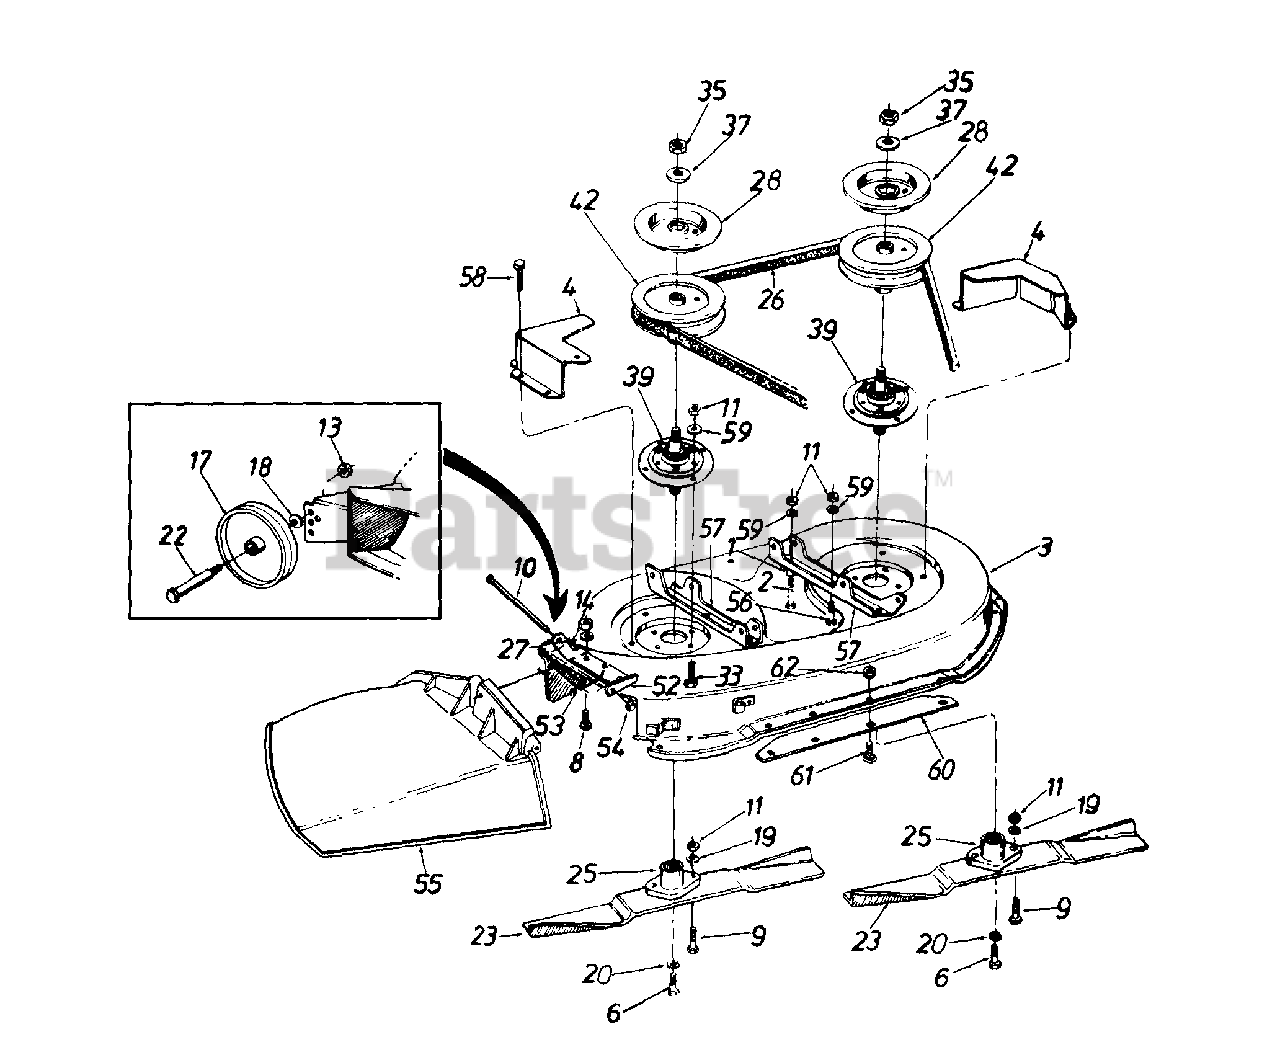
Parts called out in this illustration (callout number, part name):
1	Spacer .33" I.D. x .88"
2	Hex Bolt 5/16-24 x 1.25" Lg.
6	Hex Bolt 3/8-24 x 1.0" Lg.
8	Hex Bolt 1/4-20 x .62"
9	Hex Bolt Special 5/16-24 x 1.0"
10	Hinge Pin
11	Hex Nut 5/16-24 Thd.
13	Hex Top L-Nut 3/8-16 Thd.
14	Mex Nut 1/4-20 Thd.
17	Deck Wheel - 5"
18	Bell-Wash. .40" I.D. x .88" O.D.
19	L-Wash. 5/16" I.D.
20	L-Wash. 3/8" I.D. - H.D.
22	Shld. Bolt .498" Dia. x 1.53"
23	High-Lift Blade
25	Blade Adapter
26	V-Belt
27	Bell-Wash. 1/4" I.D.
28	Brake Disc
33	Hex Bolt 5/16-24 x .75" Lg.
35	Hex Jam Nut 5/8-18 Thd.
37	L-Wash. 5/8" I.D.
39	Blade Spindle Ass'y. Comp.
42	5" Dia. Pulley
52	Hinge Mtg. Brkt.
53	Torsion Spring
54	Push Nut
55	Chute Ass'y. Comp.
56	Hex Bolt 5/16-24 x .75" Lg.
59	Bell-Wash. .345" I.D. x .88"
62	Hex Sems Nut 1/4-20 Thd.
